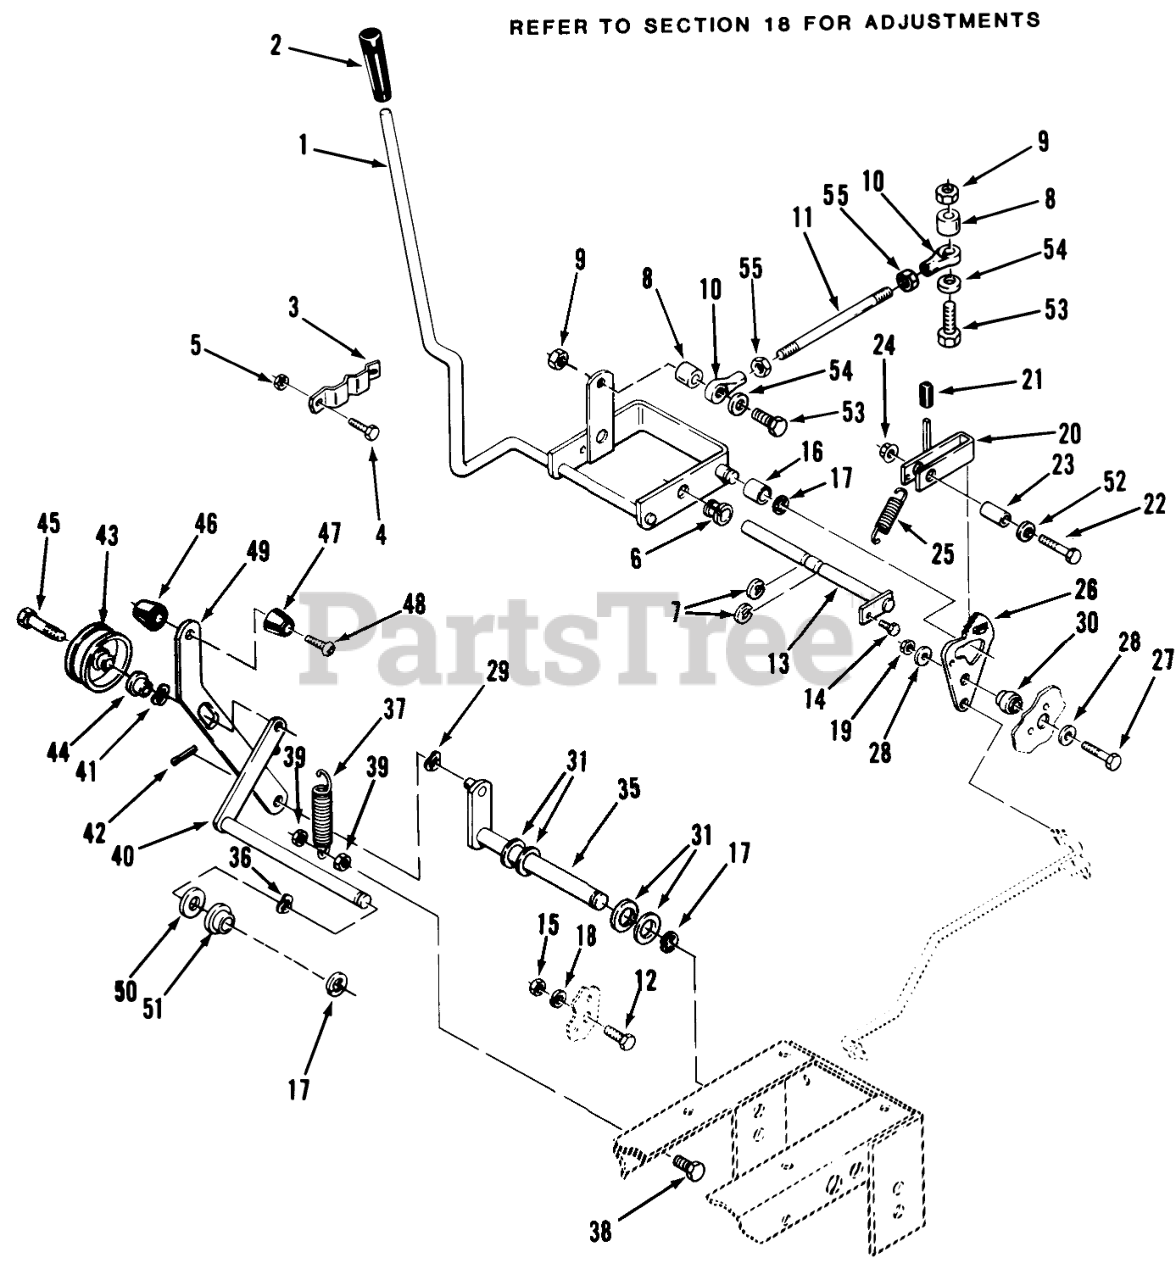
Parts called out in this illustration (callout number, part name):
1	Motion Control Lever
2	KNOB
3	Detent-Motion Control Lever
4	H H C S
5	Nut
6	NYLINER BUSHING
7	E Ring
8	Spacer
9	Nut
10	ASSY ROD END
11	ROD-CONTROL
12	Bolt
13	ASSY-ROD CAM PIVOT
14	SCREW
15	Nut
16	BEARING-CAM RETURN
17	E Ring
18	LOCKWASHER
19	Nut
20	PAWL HDL ASSY B
21	VALVE LEVER GRIP
22	Bolt
23	SPACER
24	LOCKNUT-FLANGE
25	Spring
26	Cam Plate
27	Bolt
28	Washer
29	WASHER-WAVE
30	Spacer
31	Washer
35	ASSY-BRAKE LEVER
36	WASHER-WAVE
37	SPRING-EXTENSION
38	Bolt
39	Nut
40	ASSY-ARM/ROD WA
41	WAVE WASHER
42	Cotter Pin
43	Idler Pulley
44	SPACER-BRAKE LINK
45	BOLT-SPECIAL HEX
46	KNOB
47	KNOB
48	BOLT-4
49	Handle
50	Washer
51	BUSHING-FLANGED
52	Washer
53	Bolt 1/4-20 X 1 1/2
55	Jam Nut 1/4-28
